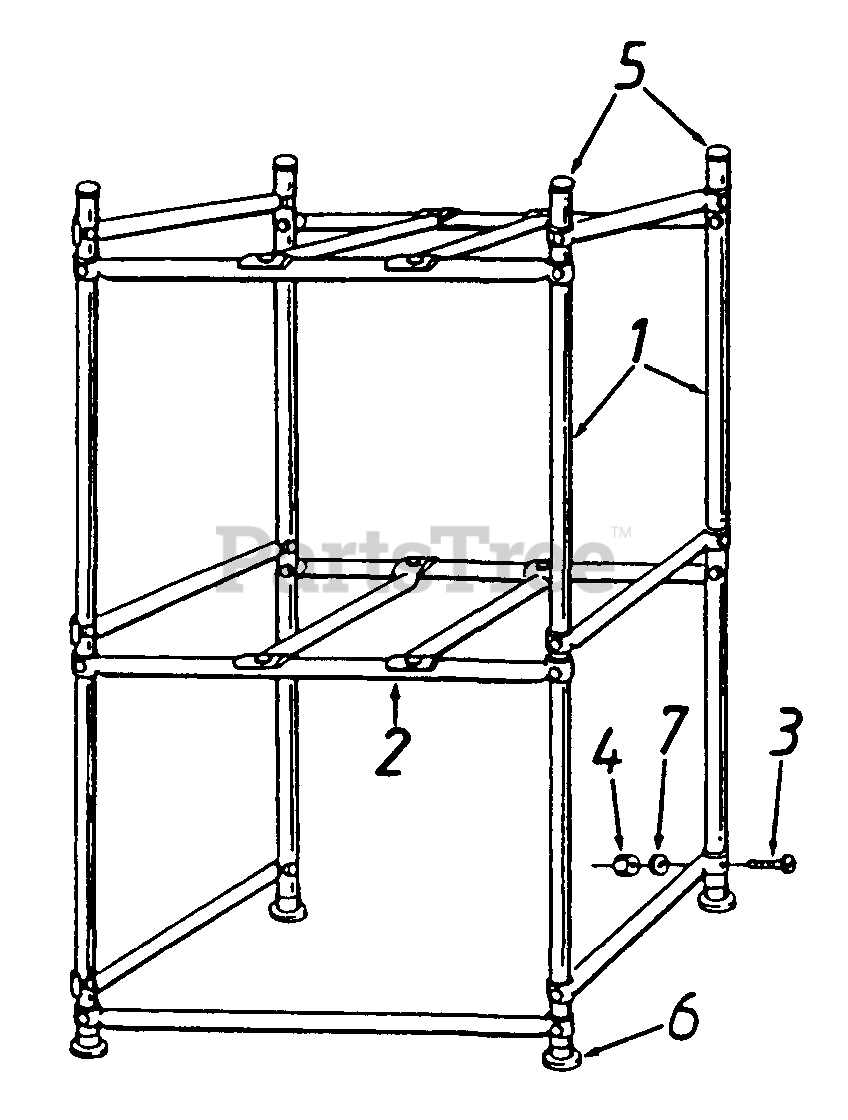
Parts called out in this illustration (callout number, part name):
4	Hex Nut 1/4-20 Thd.
5	1" Tubing Plug
6	1" Swivel Guide
7	Lock Washer 1/4" I.D.
